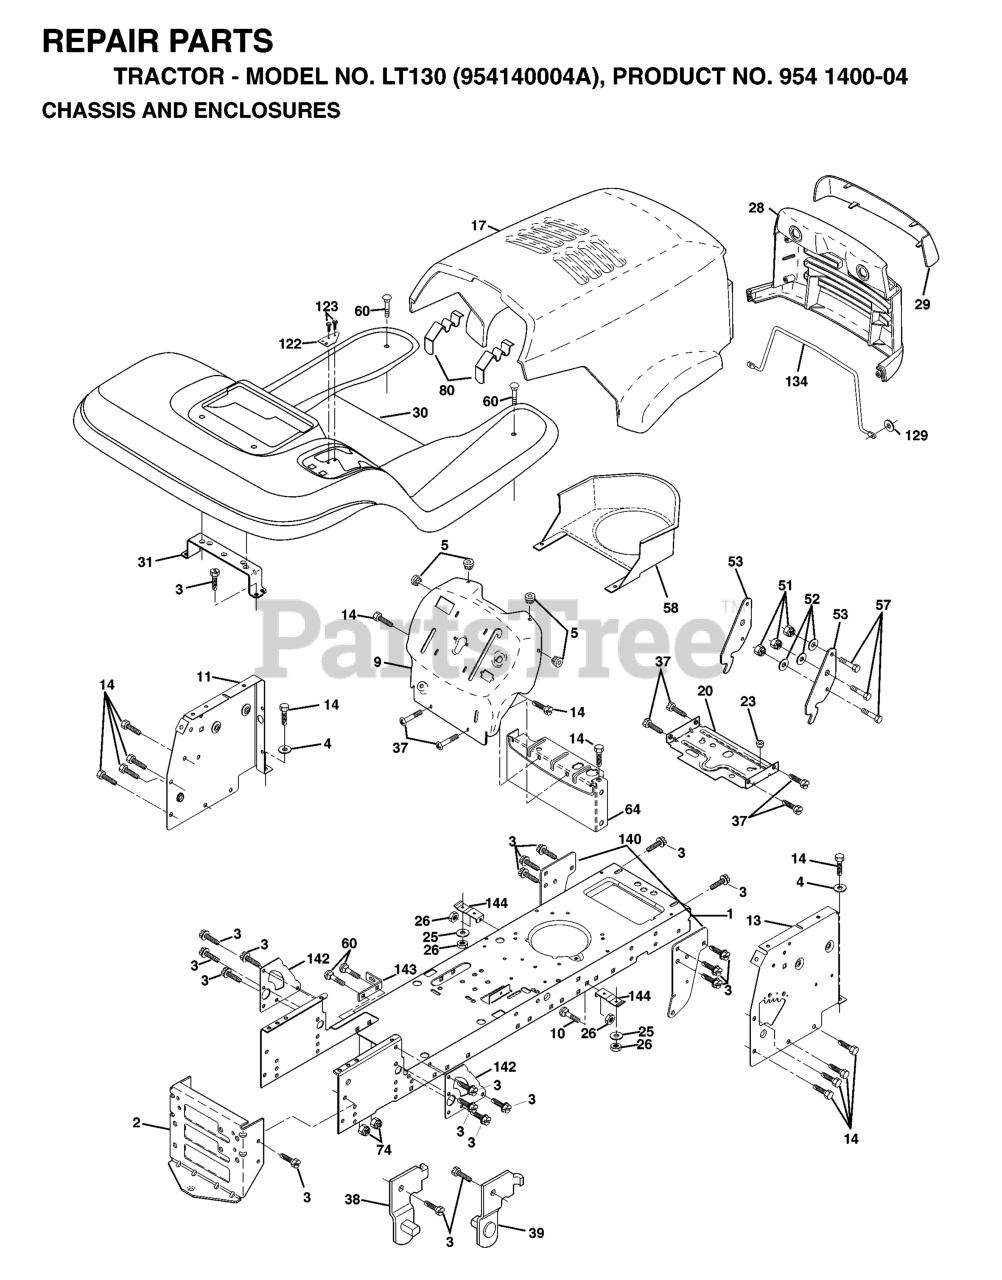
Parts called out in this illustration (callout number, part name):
1	CHASSIS WELDMENT
2	STRETCH DRAWBAR
3	SCREW
4	Washer 13/32 X 3/4 X 16 Ga.
5	BUMPER.RUBBER.HOOD
9	DASH P/L GREY LTH-120
10	BOLT D
11	PANEL DASH LH
13	PANEL DASH RH
14	SCREW LT
17	HOOD - LT/YT
20	PLATE MTG
23	BUSHING.SNAP.NYL.BLK.
25	WASHER
26	NUT
28	GRILLE LT/PL HUSQVARNA
29	LENS LT/PL HUSQVARNA
30	FENDER FOOTREST
31	BRACKET.SUPPORT.FENDER
37	Screw 5/16-18 x 1/2 Hex, Self Tapping 5/16-18 x 1/2
38	BRACKET LH PIVOT
39	BRACKET RH PIVOT
51	LOCKNUT.NYLOC.1/4-20
52	WASHER
53	BRACKET PNT PICK OFF LT/PL
57	BOLT
58	AIR DUCT P/L/LT
60	Bolt - Rd. Hd. Sq. Neckiage 3/8 16 x 3/4
64	DASH LOWER
80	LATCH HOOD
129	WASHER
134	ROD SUPPORT HOOD LT/PL HUSQ
140	BRACKET CHASSIS FRONT
142	PLATE REINFORCEMENT
143	BRACKET, SWAY BAR
144	BRACKET FOOTREST
146	SCREW TORX HD 5/16X18
